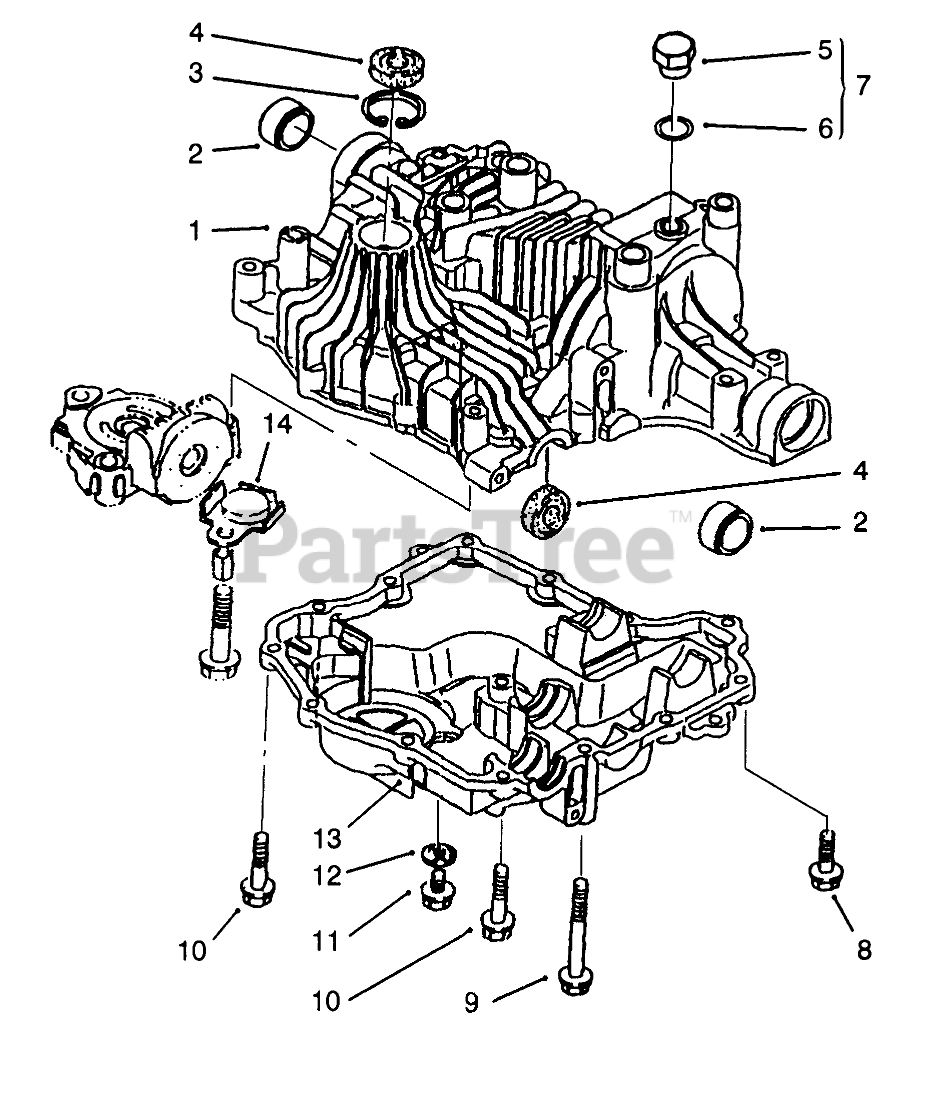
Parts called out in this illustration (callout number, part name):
1	ASM - UPPER CASE INC 2-6
3	RING
4	SEAL
5	Plug
6	Packing
7	PLUG-PACKING
8	SCREW-TAP
10	SCREW-TAP
13	CASE - LOWER
14	MAGNET
